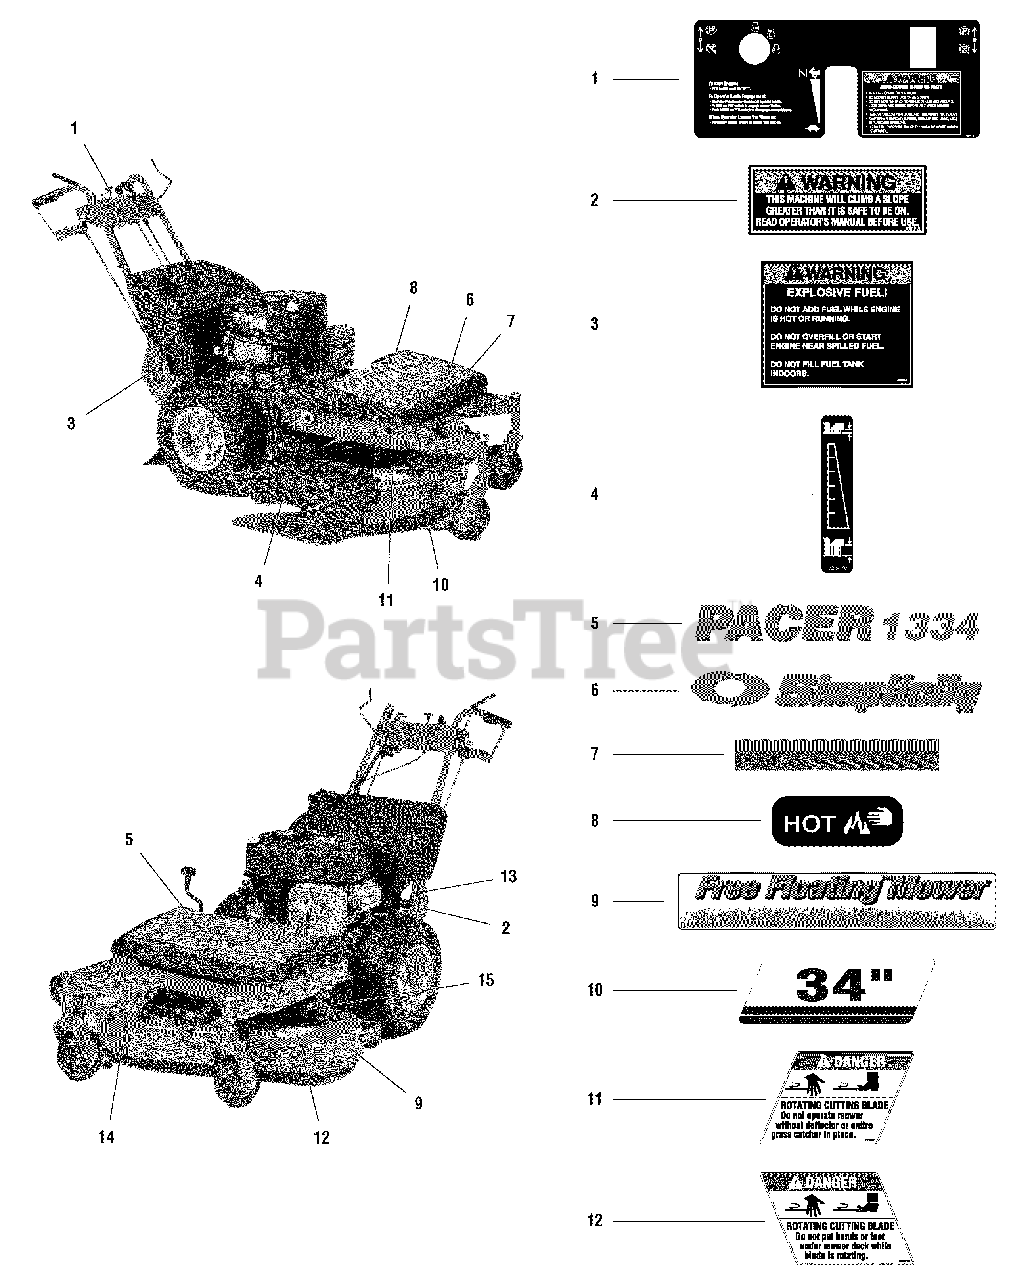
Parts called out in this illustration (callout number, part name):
1	DECAL, Control Panel
2	DECAL, Warning Machine Climb
3	DECAL, Warning Explosive Fuel
4	DECAL, Height Of Cut
5	DECAL, Pacer 1334
6	DECAL, Simplicity, Silver & Blue, W/Icon
7	DECAL, Stripe, Blue & Silver
9	DECAL, Free Floating
11	DECAL, Danger (Chute In Place)
12	DECAL, Danger (Hand Under Deck)
13	MODEL/SERIAL TAG (Not Serviced)
14	DECAL, OPEI (Not Serviced)
15	DECAL, ID Plate
